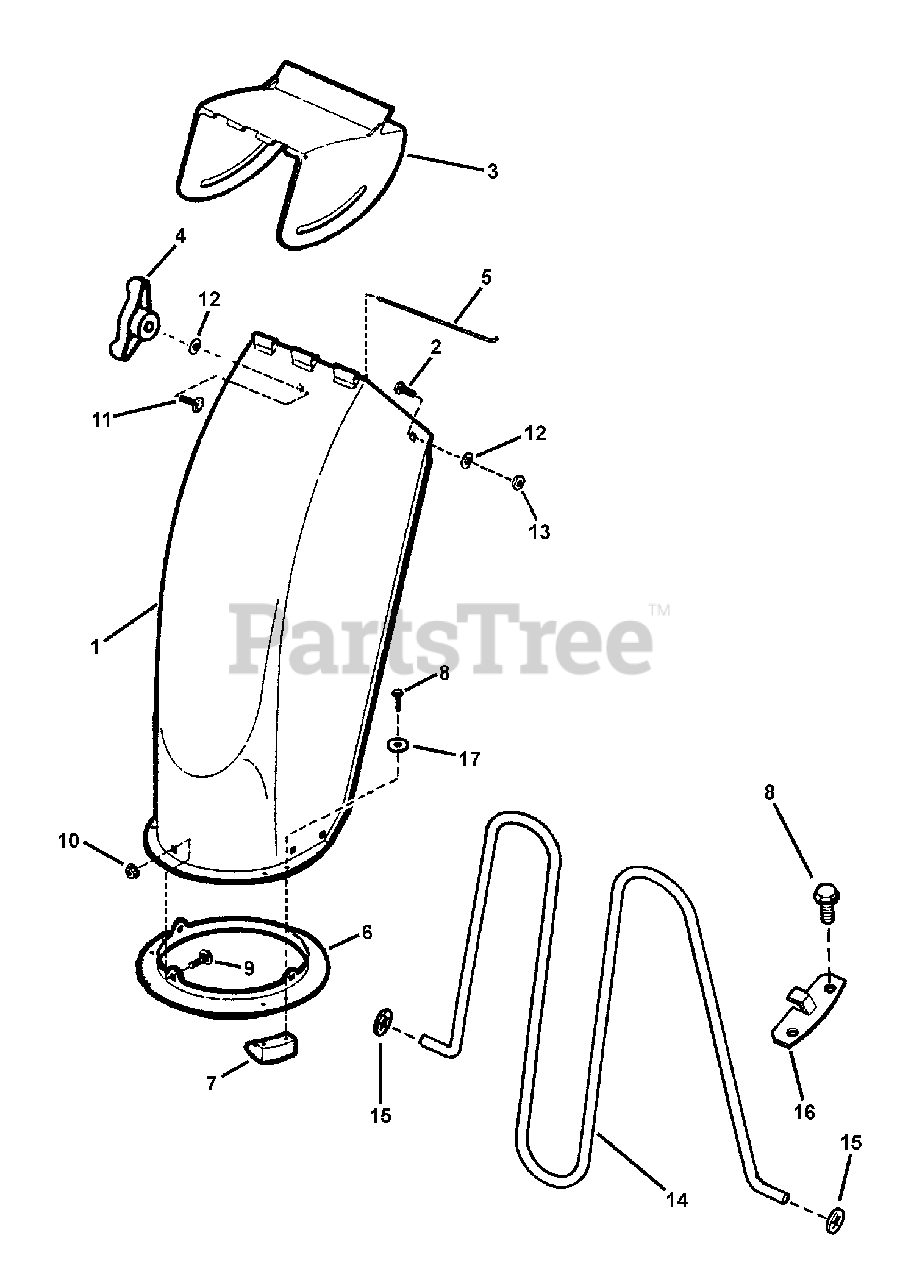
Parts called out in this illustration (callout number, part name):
1	*CHUTE, Discharge
2	SCREW, 5/16-24 x 3/4" Hex Head Cap, GR 5
3	DEFLECTOR, Chute
4	WING KNOB, 5/16-18
5	WIRE PIN
6	CHUTE RING
7	RETAINER, Spout
8	SCREW, #10-24 x 5/8" Hex Washer Self-Tap
9	BOLT, 5/16-18 x 5/8" Square Neck Carriage, GR 5
10	NUT, 5/16-18 Hex Flange Lock
11	BOLT, 5/16-18 x 3/4" Square Neck Carriage, GR 5
12	WASHER, .34 x .69 x .08 Flat
13	NUT, 5/16-24 Hex Center Lock, GR B
14	WIRE, Safety
15	PUSH-ON FASTENER, 5/32" Dia.
16	RETAINER, Safety Wire
17	WASHER, 7/32" Flat
